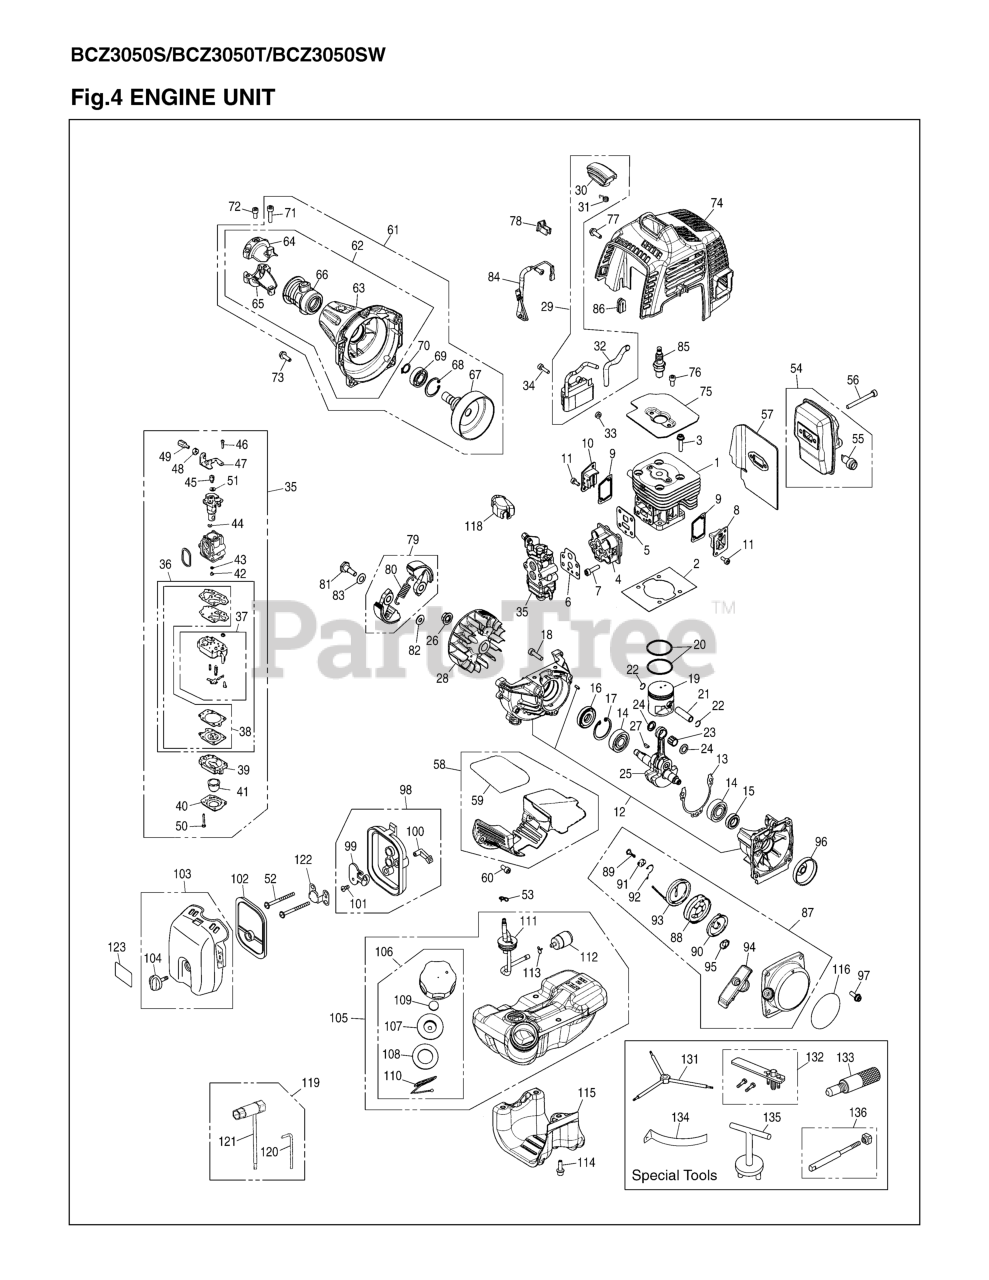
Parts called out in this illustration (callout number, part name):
2	GASKET, BASE
3	BOLT
4	INSULATOR
5	GASKET, INSULATOR
6	GASKET
7	BOLT, TORX
8	COVER, TRS
9	GASKET, TR
10	COVER, TRF
11	BOLT
12	CRANKCASE COMP
13	GASKET, CASE
14	BEARING
15	SEAL
16	SEAL
17	SNAP RING
18	BOLT TORX
20	RING
22	RING, SNAP
23	BEARING
24	WASHER
25	CRANKSHAFT COMP
26	NUT
27	KEY
28	ROTOR
29	COIL-A
30	CAP
31	SPRING
33	SPACER
34	BOLT TORX
35	CARBURETOR ASSY
36	REBUILD KIT
37	BODY ASSY
38	GASKET KIT
39	BODY, PURGE
40	COVER, PUMP
41	PUMP, PRIMING
42	JET
43	O-RING
44	RING
45	SWIVEL
46	SCREW
48	NUT
49	SCREW, CABLE ADJUSTER
50	SCREW
51	WASHER
52	BOLT TORX
53	CLIP
54	MUFFLER ASSY
55	ARRESTER
56	BOLT TORX
58	PLATE ASSY
59	SHEET
60	BOLT TORX
61	HOUSING ASSY
62	HOUSING COMP.
63	HOUSING
64	BRACKET (A)
65	BRACKET (B)
66	CUSHION
67	DRUM
68	RING
69	BEARING
70	SNAP RING
71	BOLT TORX
72	BOLT TORX
73	BOLT
74	COVER, ENGINE
75	PLATE, CYL
76	BOLT TORX
77	BOLT, TORX
78	CLAMP
79	SHOE
80	SPRING
81	SCREW
82	WASHER
83	WASHER
84	CORD COMP.
85	SPARK PLUG
86	GROMMET
87	RECOIL ASSY
88	REEL
89	SCREW
90	SPRING
91	COLLAR
92	ARM
93	ROPE
94	KNOB
95	PLATE
96	PULLEY
97	BOLT, TORX
98	CLEANER BODY ASSY
99	PLATE, CHOKE
100	LEVER
101	SCREW
102	ELEMENT
103	CLEANER COVER ASSY
104	CLEANER KNOB
105	TANK ASSY
106	CAP ASSY
107	HOLDER ASSY
108	PACKING
109	FILTER
110	STOPPER
111	PIPE COMP
112	FUEL FILTER (BLK SLEEVE)
113	CLIP
114	BOLT TORX
115	GUARD, TANK
116	LABEL, RECOIL
118	COVER
119	TOOL SET
120	BAR
121	SOCKET
123	LABEL, CAUTION
131	HEXAGON WRENCH
132	PULLER ASSY
133	STOPPER
135	PULLER
136	ROD ASSY
